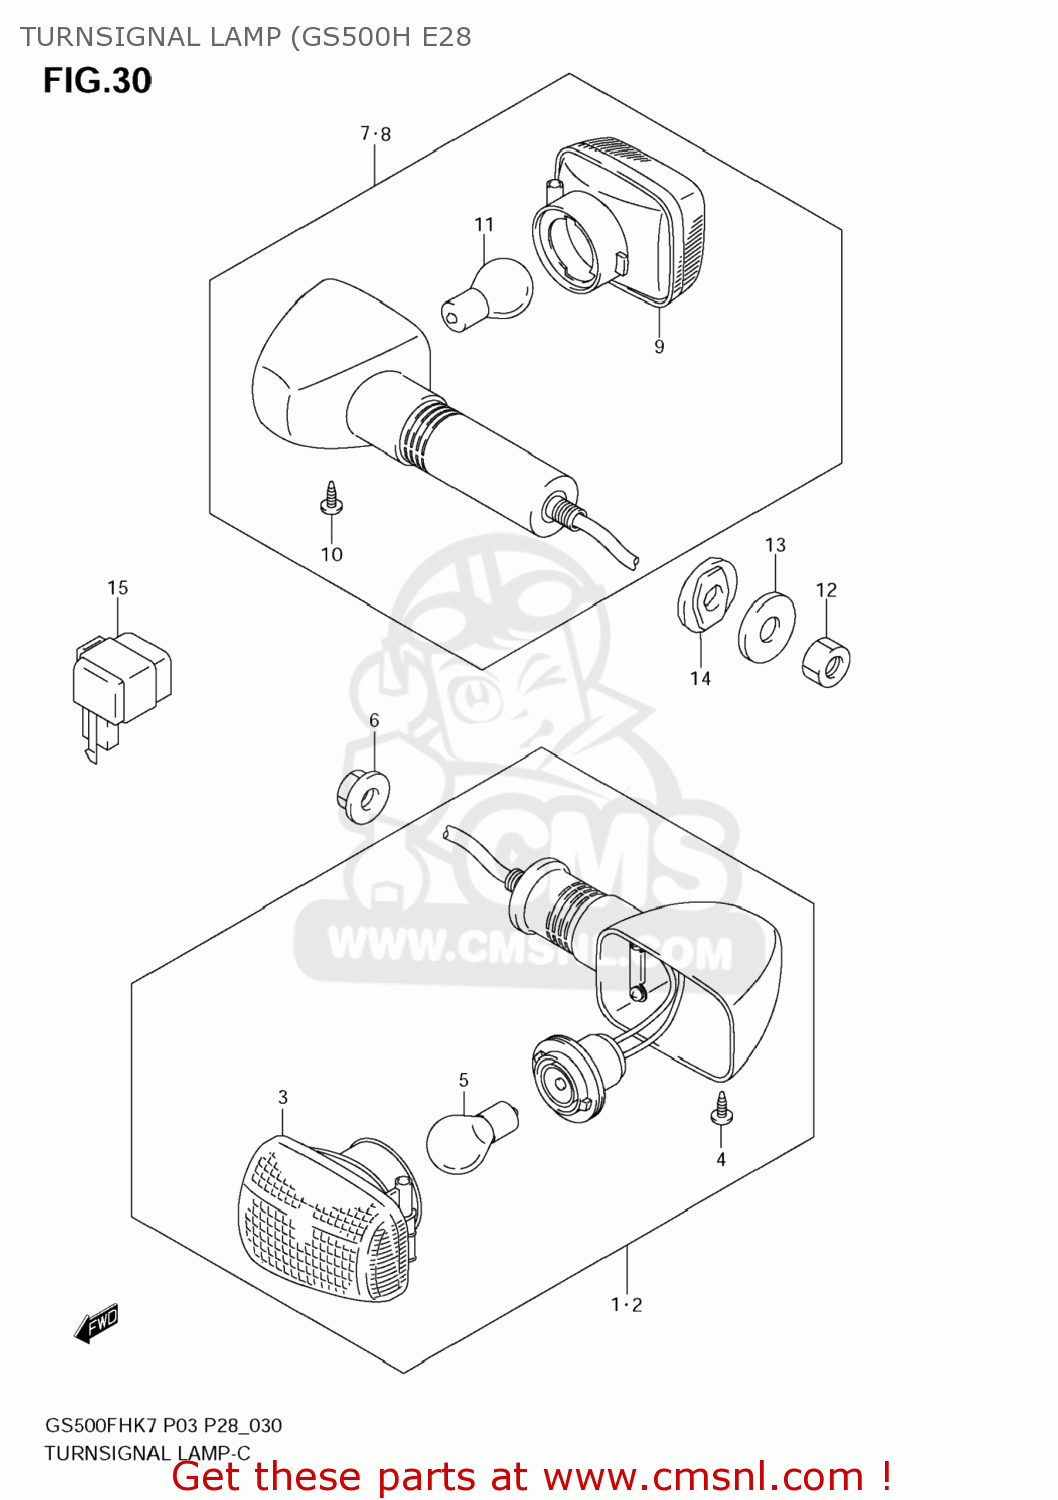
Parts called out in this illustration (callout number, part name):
1	TURNSIGN FR RH
2	LAMP ASSY, FRONT LH
3	LAMP UNIT
4	SCREW
5	BULB(12V21W)
6	NUT
7	LAMP ASSY REAR
8	LAMP ASSY REAR
9	LAMP UNIT
10	SCREW
11	BULB(12V21W)
12	NUT
13	WASHER(10.5X30X2.3)
14	SPACER,RR TURNSIGNAL
15	RELAY ASSY, TURNSIGNAL
